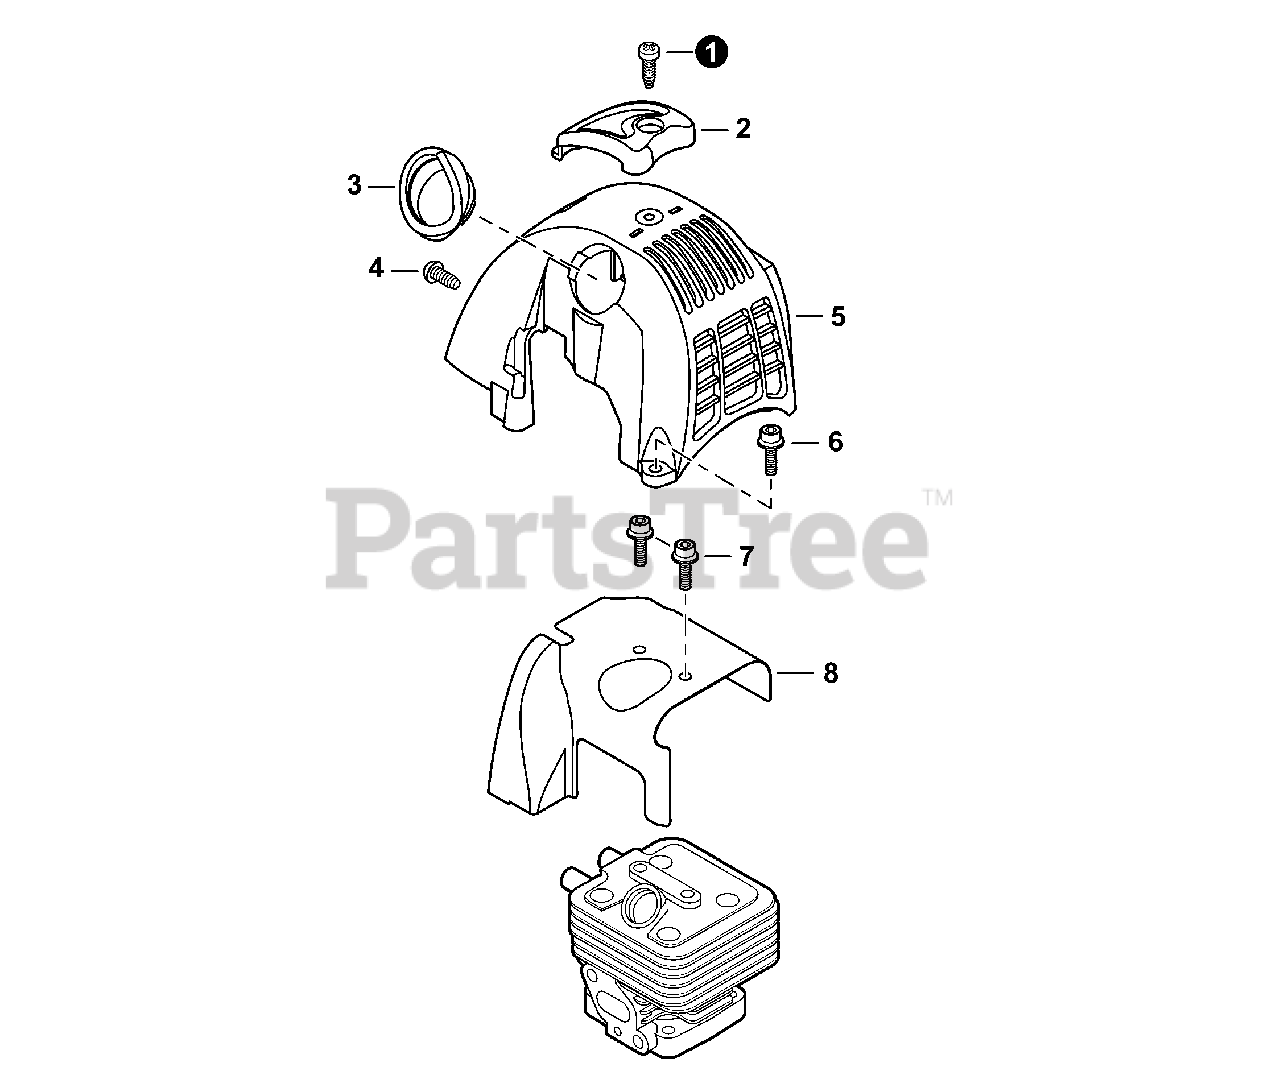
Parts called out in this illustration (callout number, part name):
1	SCREW, TAPPING 5×16
2	GUARD, TOP
3	GUARD, TOP - SPARK PLUG
4	BOLT 5×12
5	COVER, ENGINE
6	BOLT 5×14
7	BOLT 5×8
8	SHIELD, CYLINDER
